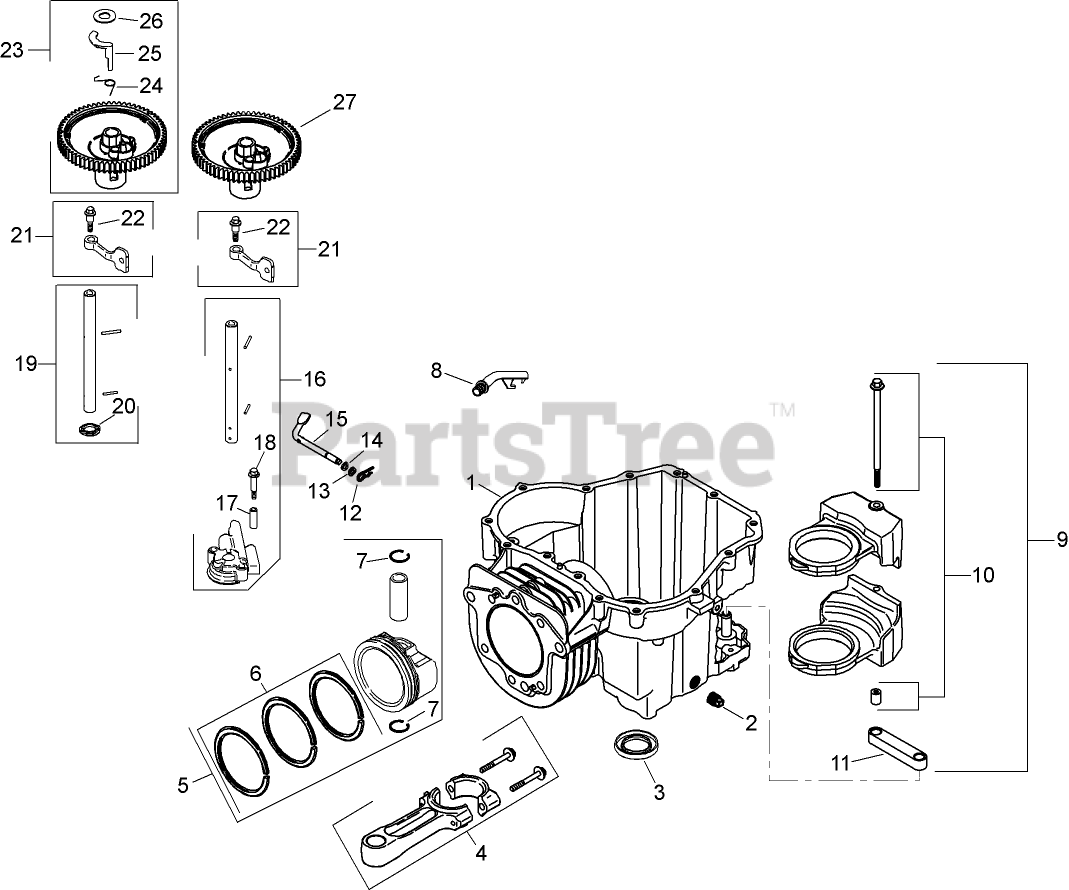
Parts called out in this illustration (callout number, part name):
1	Loose Parts Package
2	PLUG-PIPE, SQ HD (3/8)
3	Seal-Oil
4	Connecting Rod ASM
5	Piston w/Ring Set (94 mm) (Includes 6-7)
6	Ring Set (94 mm)
7	Retainer-Pin, Piston
8	Tube-Back, Drain
9	Balance Weight Kit (Includes 10-11)
10	LOCATING PIN ASM
11	LINKAGE-WEIGHT, BALANCE
12	Clip-Pin, Hitch
13	WASHER-FLAT (6mm)
14	WASHER-FLAT (1/4)
15	Shaft-Cross, Governor
16	Oil Pump ASM (Includes 17-18)
17	Spacer-Screw, Oil Pump
18	Screw-Pump, Oil
19	Shaft-Cam, Center - Exhaust (Includes 20)
20	WASHER-THRUST
21	Cam Lever ASM (Includes 22)
22	Bolt-Shoulder (M6x1x26)
23	CAM GEAR ASM (EXHAUST) (INCLUDES REF 19, 21, 24)
24	Spring-A C R
25	Weight-A C R
26	Washer-Thrust, A C R
27	CAM GEAR ASM (INTAKE)
